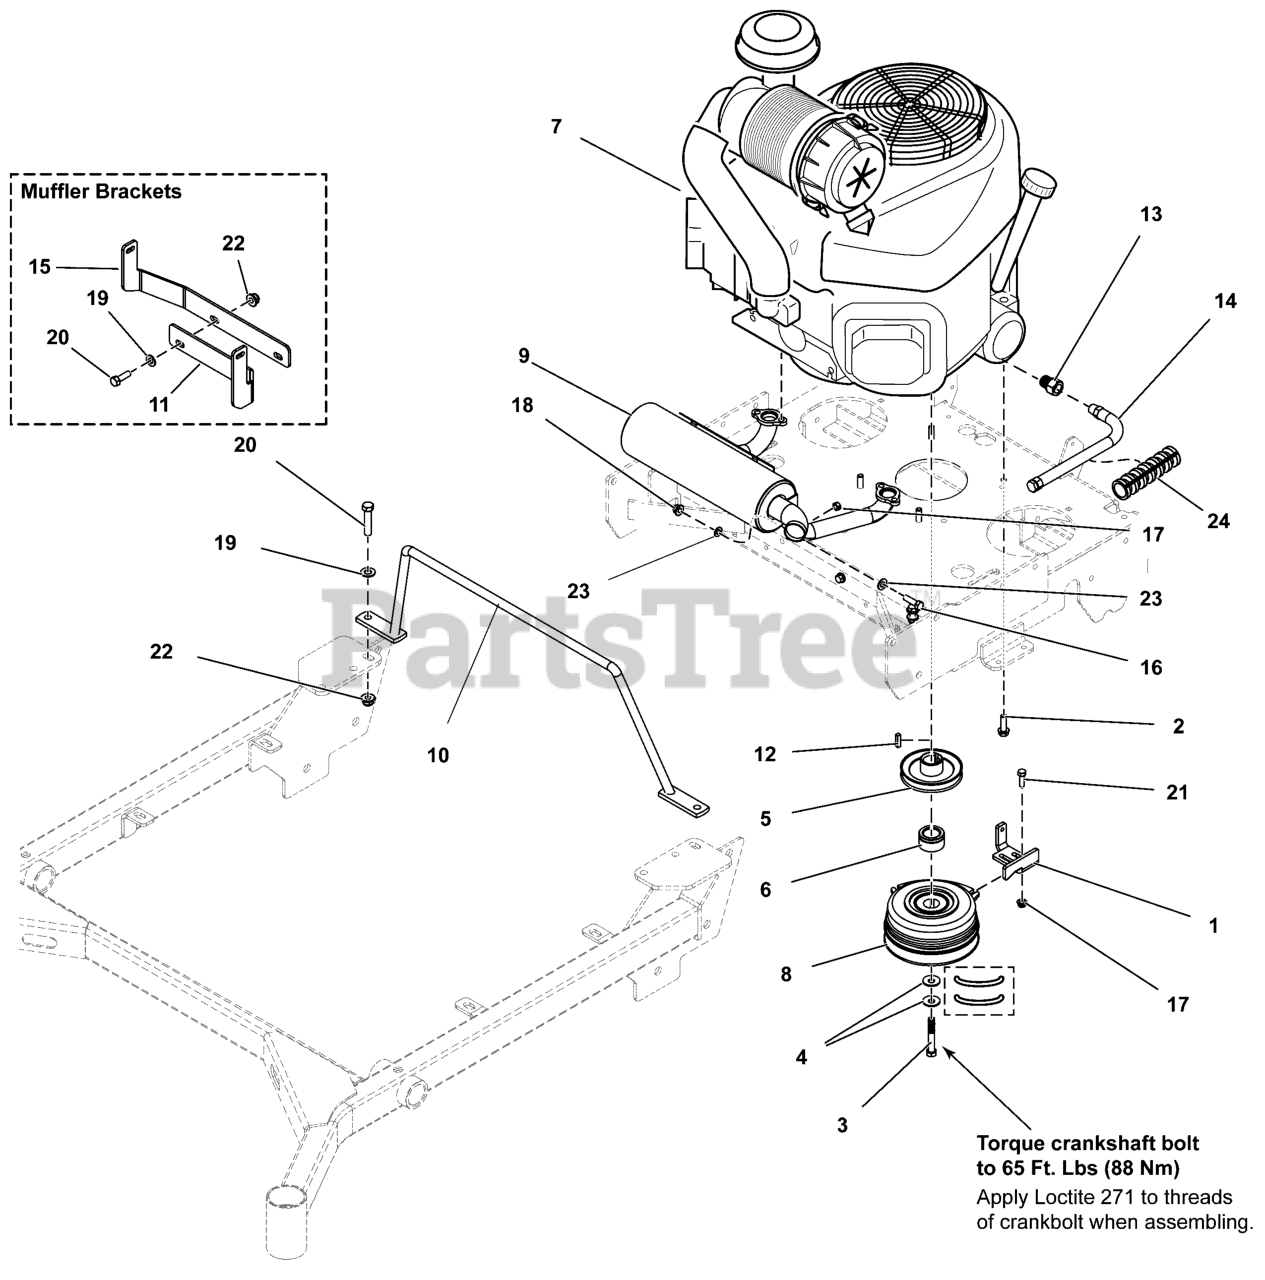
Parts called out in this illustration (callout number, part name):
1	PLATE, CLUTCH ANCHOR - BLK
2	BOLT, 3/8-16X1-1/4 SF, GD8, PHOS, SER HD
3	BOLT, CRANKSHAFT, 7/16 X 2-3/4, PATCH, CZ
4	BELLEVILLE WASHER, 1.1875 X .442 X .098
5	PULLEY, CRANKSHAFT, 1.125ID X 4.50OD, OS
6	SPACER, 1.13 X 1.75 X 1.03, CZ
8	CLUTCH WARNER 200 FT-LB 1.13 X 6.323
9	MUFFLER, HORIZONTAL, KAWASAKI
10	WELD, MUFFLER GUARD - BLK
11	PLATE, MUFFLER SUPPORT, LH, W35 - BLKK
12	KEY, 1/4 SQ X 1
13	ADAPTER, Oil Drain
14	HOSE, OIL DRAIN
15	PLATE, MUFFLER SUPPORT, RH, W35 - BLK
16	BOLT, 5/16-18 X 1" GRD5 YZ
17	NUT, 5/16-18 HEX NYLOCK FLANGE NUT
18	NUT, 5/16-1/8, HEX, CNTR LK, ZINC PHOS/OIL
19	WASHER, 3/8 SAE
20	BOLT, 3/8-16 X 1-1/4" GD5 CZ
21	BOLT, 5/16-18 X 1, CARRIAGE, GD5, CZ
22	NUT, 3/8 - 16 HEX NYLOCK FLANGE
23	WASHER, 5/16 GRADE 9, FLAT
24	WIRE LOOM, 3/4 ID X 8.00" LG
